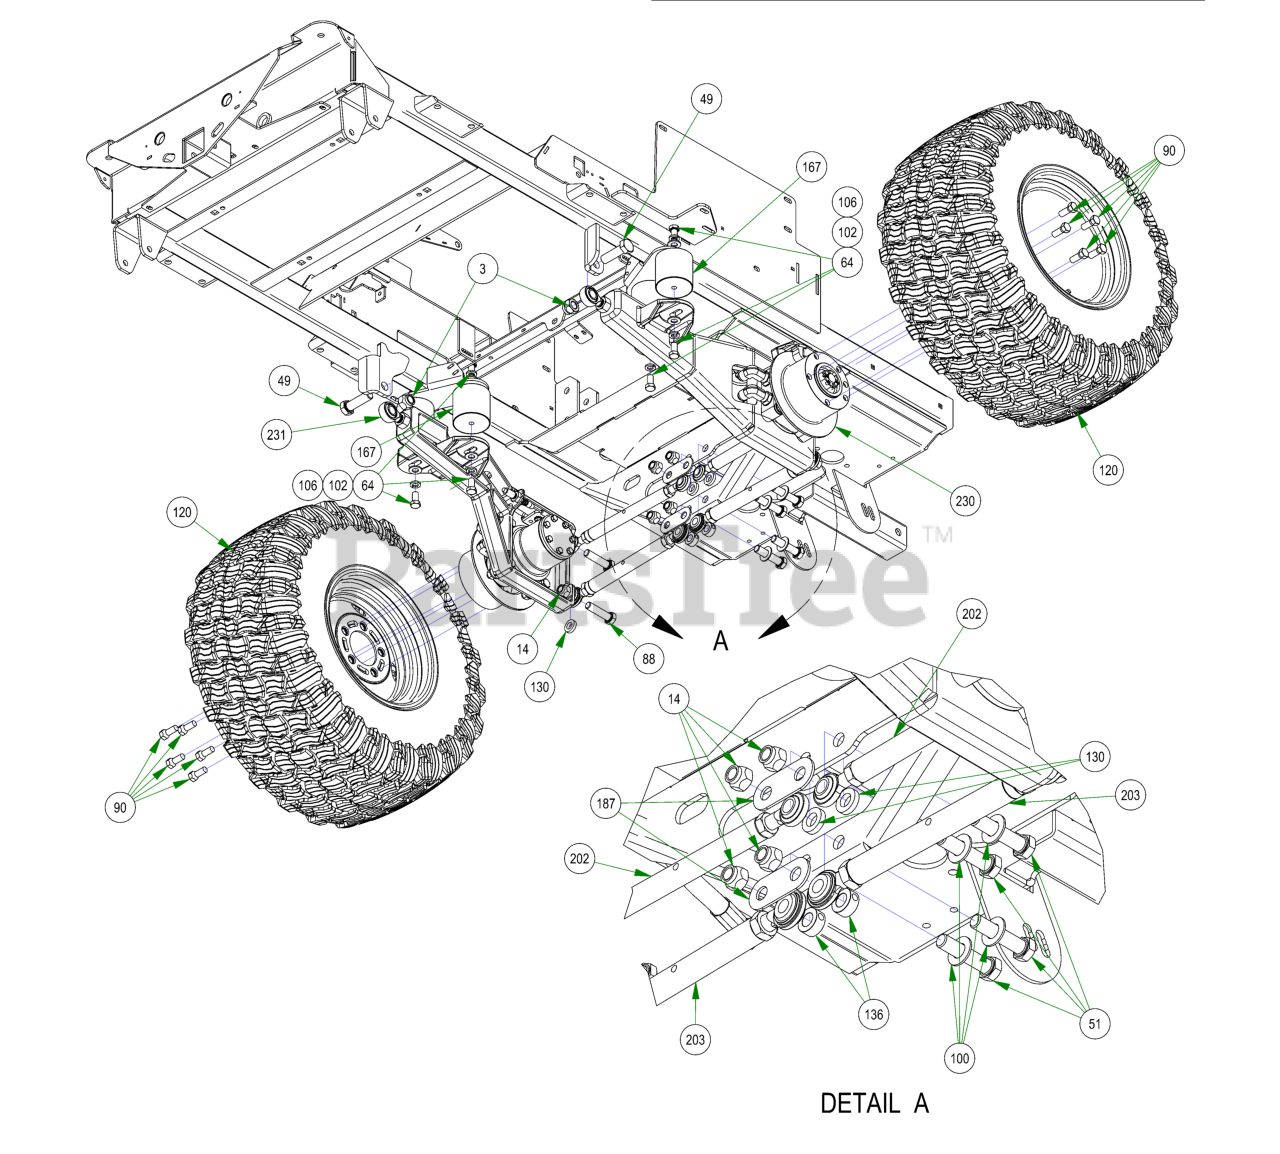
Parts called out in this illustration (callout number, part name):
3	3/4-10 NYLON INSERT LOCKNUT ZINC
14	5/8-11 NYLON INSERT LOCKNUT ZINC
49	3/4-10 X 2-1/2 HEX CAP SCREW (GR.5) ZINC
51	5/8-11 X 2-3/4 HEX CAP SCREW (GR.5) ZINC
64	1/2-13 X 1 HEX CAP SCREW (GR.5) ZINC
88	5/8-11 X 2-1/2 HEX CAP SCREW (GR.5) ZINC
90	1/2-20 x 60° Lug Bolts Zinc Grade 8
100	5/8" Flat Washer SAE Spec Grade 8
102	1/2 SPLIT LOCKWASHER (GR.8) ZINC/YELLOW
106	1/2 SAE FLAT WASHER (1-1/16" OD) GR.8 ZINC YELLOW
120	2019 Assy-26x12-12 Reaper Turf -10.5" Rim
130	Spacer 1.125OD x .625 ID x .250 Length
136	5/8 SOLID SHAFT COLLAR (W/1 SET SCREW) ZINC
167	Vibration Mount-Blue Dot
187	2019 Suspension Gusset Outlaw
202	2019 Suspension Radius Rod Assembly
203	2019 Suspension Radius Rod Assembly
230	2019 Renegade Trailing LH Arm Assy
230.4.1	1" Castle Nut for HydroGear Wheel Motor
230.4.2	Woodruff Key
231	2019 Renegade Trailing RH Arm Assy
231.4.1	1" Castle Nut for HydroGear Wheel Motor
231.4.2	Woodruff Key
234	2022 Horizontal Diesel Frame
